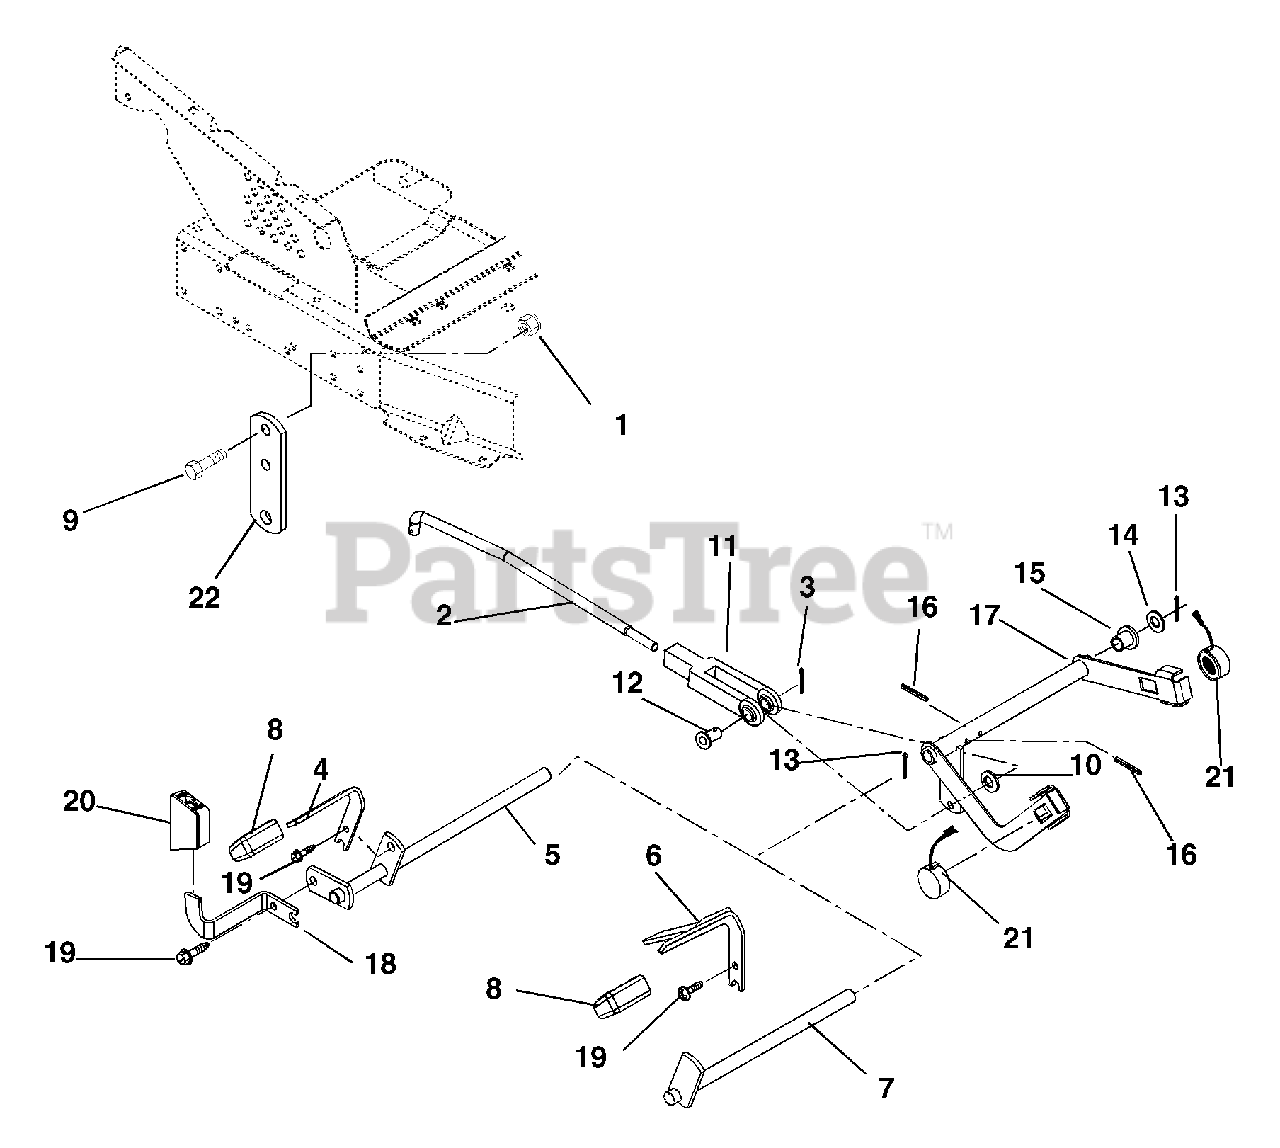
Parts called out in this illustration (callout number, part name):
1	@NUT-LK-CTR .38-16 YWZC
2	ROD, SHIFT
3	@PIN-CTR .09X.75 EXTPRSQCT YWZ
4	PEDAL, FORWARD
5	SHAFT - PEDAL
6	PEDAL-F/R HI SIERRA COMP
7	SHAFT-PEDAL (SINGLE)
8	COVER - PEDAL - FORWARD
9	@BLT-HEX .38-16X.75 GR5 YWZC
10	WSHR-FL-STL .390X.75X.125 YWZC
11	YOKE, .312-24 X 2.25
12	PIN-CLEV .31X.937 FLHD YWZC
13	@PIN-CTR .12X1.00 EXTPRSQCT YZ
14	WSHR-FL-STL .52X.827X.062 YWZC
15	BSHG-FLG .515X.750X.745X1.00NY
16	PIN-GRV .188X1.25 TP A
17	ASSEMBLY, SHIFT ARM
18	PEDAL-REVERSE
19	@SCR-TAP .38-16X.75 HWH TR YWZ
20	COVER - PEDAL - REVERSE
22	BRACKET, HANGER
